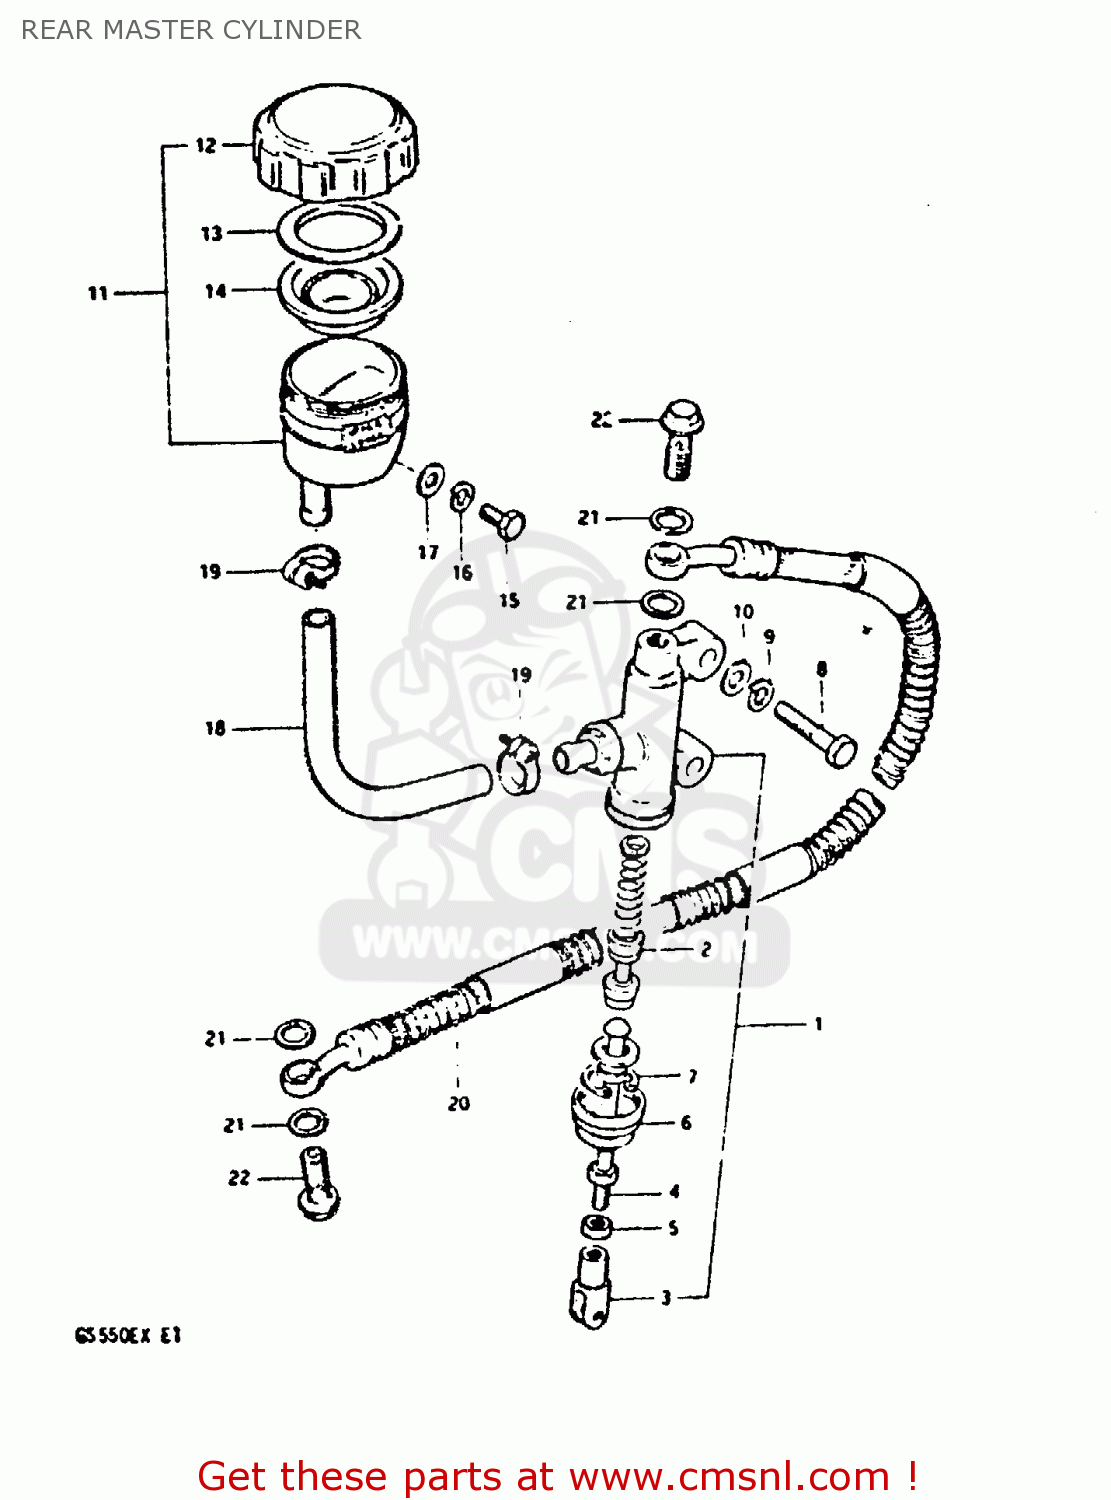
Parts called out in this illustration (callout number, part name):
1	CYLINDER ASSEMBLY,REAR MASTER
2	PISTON/CUP SET
3	YOKE
4	ROD,PUSH
5	NUT
6	BOOT
7	CIRCLIP
8	BOLT (8X30)
9	LOCK WASHER
10	WASHER
11	TANK ASSEMBLY,RESERVOIR
12	CAP
13	PLATE,DIAPHRAGM
14	DIAPHRAGM
15	BOLT, UPPER
16	LOCK WASHER
17	WASHER
18	HOSE,RESERVOIR TANK
19	CLAMP
20	HOSE,REAR BRAKE
21	WASHER
22	BOLT,UNION
